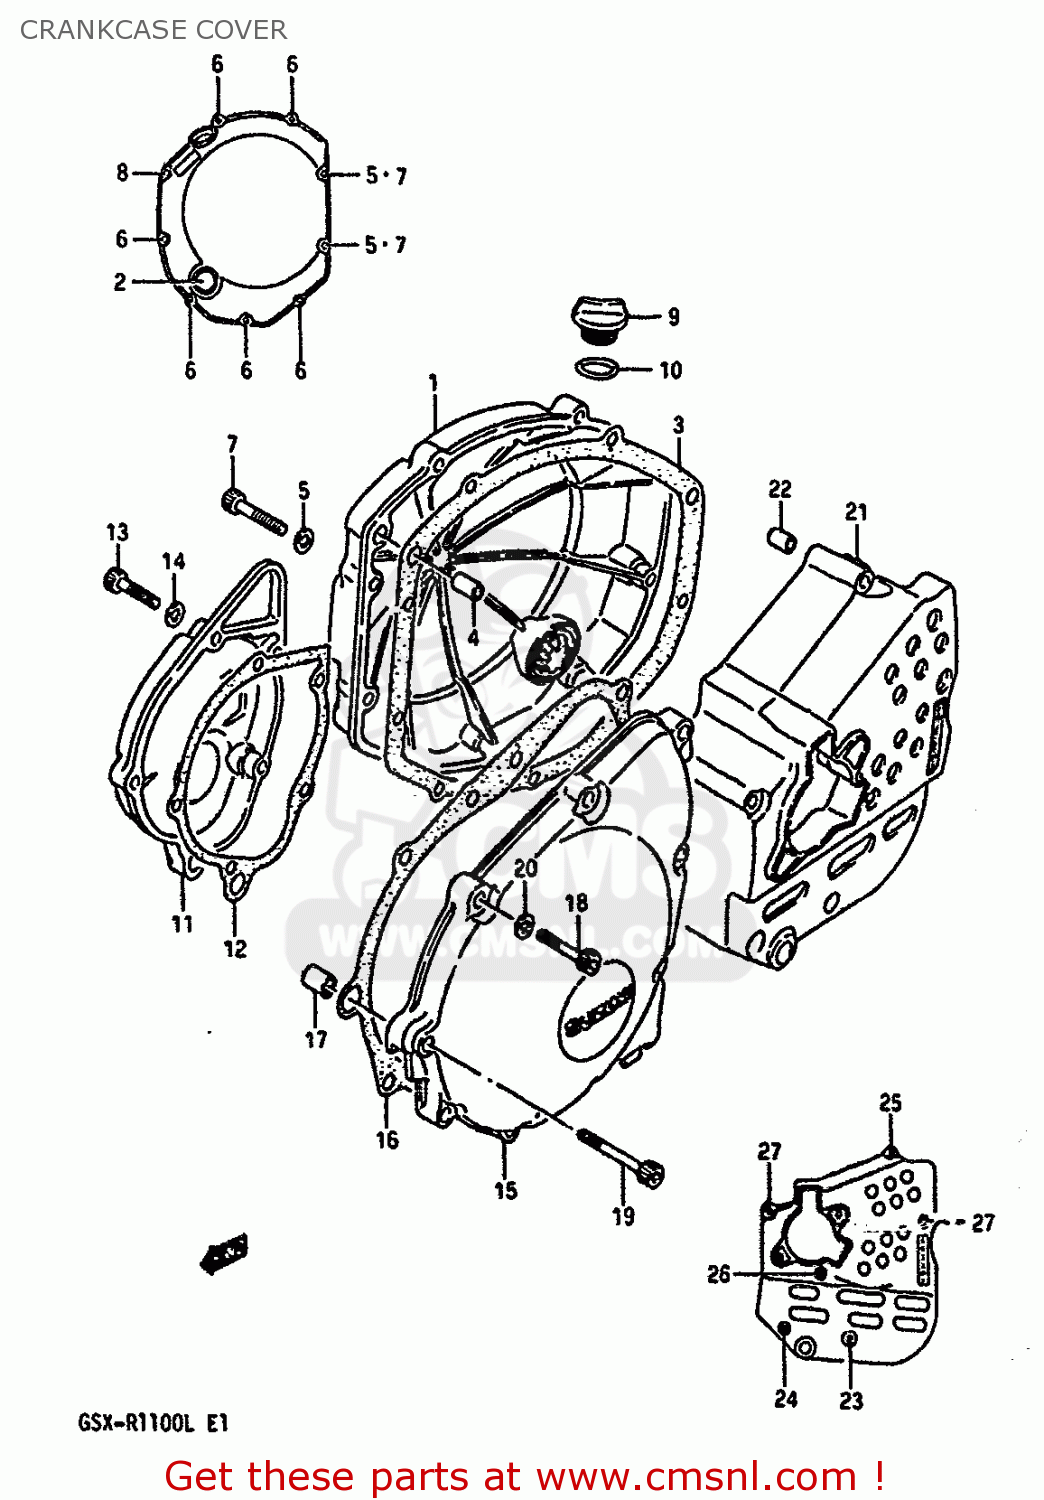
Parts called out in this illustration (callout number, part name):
1	COVER,CLUTCH
2	LENS,OIL LEVEL CHECK
3	GASKET,CLUTCH COVER (MCA)
4	PIN
5	GASKET(5.8X11X1.2) (NAS)
6	BOLT
7	BOLT
8	BOLT
9	PLUG
10	O RING(D:3.1,ID:16.8)
11	COVER,SIGNAL GENERATOR
12	GASKET,SIGNAL GENERATOR COVER
13	BOLT
14	GASKET(5.8X11X1.2) (NAS)
15	COVER,STARTER GEAR
16	GASKET,STARTER GEAR COVER
17	PIN (11X20)(SUS)
18	BOLT
19	BOLT
20	GASKET(5.8X11X1.2) (NAS)
21	COVER,SPROCKET
22	PIN
23	BOLT
24	BOLT
25	BOLT
26	BOLT
27	BOLT
